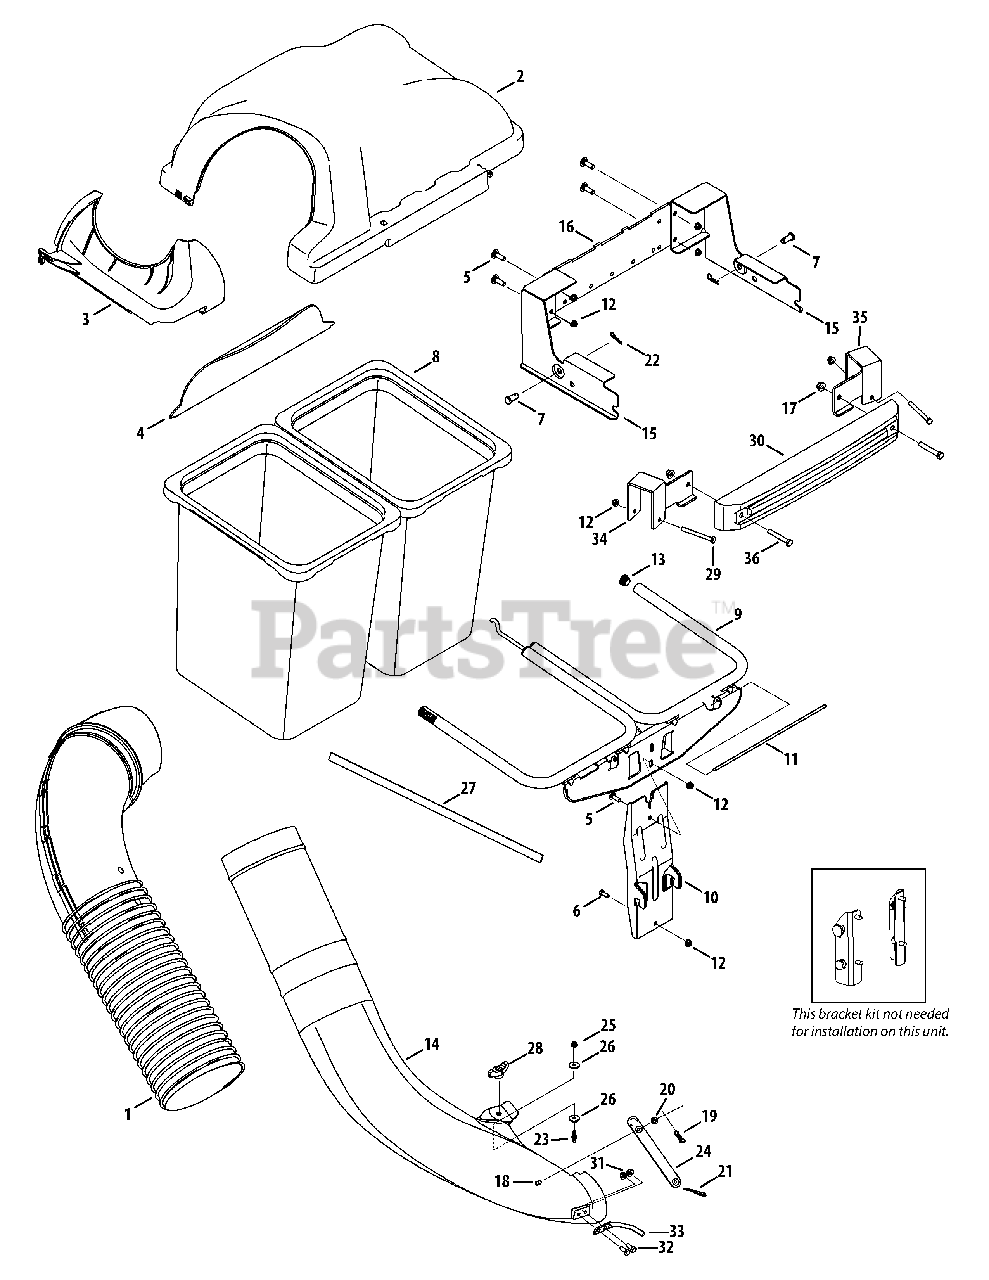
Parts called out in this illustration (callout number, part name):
1	Upper Chute Assembly
2	Twin Bagger Cover Assembly
3	Upper Chute Support
4	Bagger Cover Screen
5	Carriage Screw, 5/16-18 x 1.00"
6	Hex Head Screw, 5/16-18 x 1.00"
7	Clevis Pin, .50" Dia. x 1.18
8	Grass-bag Assembly
9	Twin Bag Support Assembly
10	Vertical Support Bracket
11	Cover Hinge Pin
12	Flange Lock Nut, 5/16-18
13	End Plug
14	Discharge Chute Elbow
15	RZT Hitch Bracket Kit
16	Universal Cross Bracket
17	Flange Lock Nut, 3/8-16
18	Clevis Pin 5/16 x 3/4
19	Bow-Tie Cotter Pin
20	Flat Washer, .344 x .62 x .033
21	Torsion Spring Hook
22	Cotter Pin, .080 x 1.5625 Internal
23	Grass-catcher Pin
24	Chute Strap
25	Flange Lock Nut, 1/4-20
26	Flat Washer
27	Foam Strip
28	Wing Knob,
29	Hex Head Screw, 5/16-18 x 3.25
30	RZT Bagger Weight
31	Flange Lock Nut
32	Screw 1/4-20 x .750
33	Rod, Lower Chute
34	Wt. Mount Bracket, RH
35	Wt. Mount Bracket, LH
36	Hex Head Screw, 3/8-16 x 2.50
